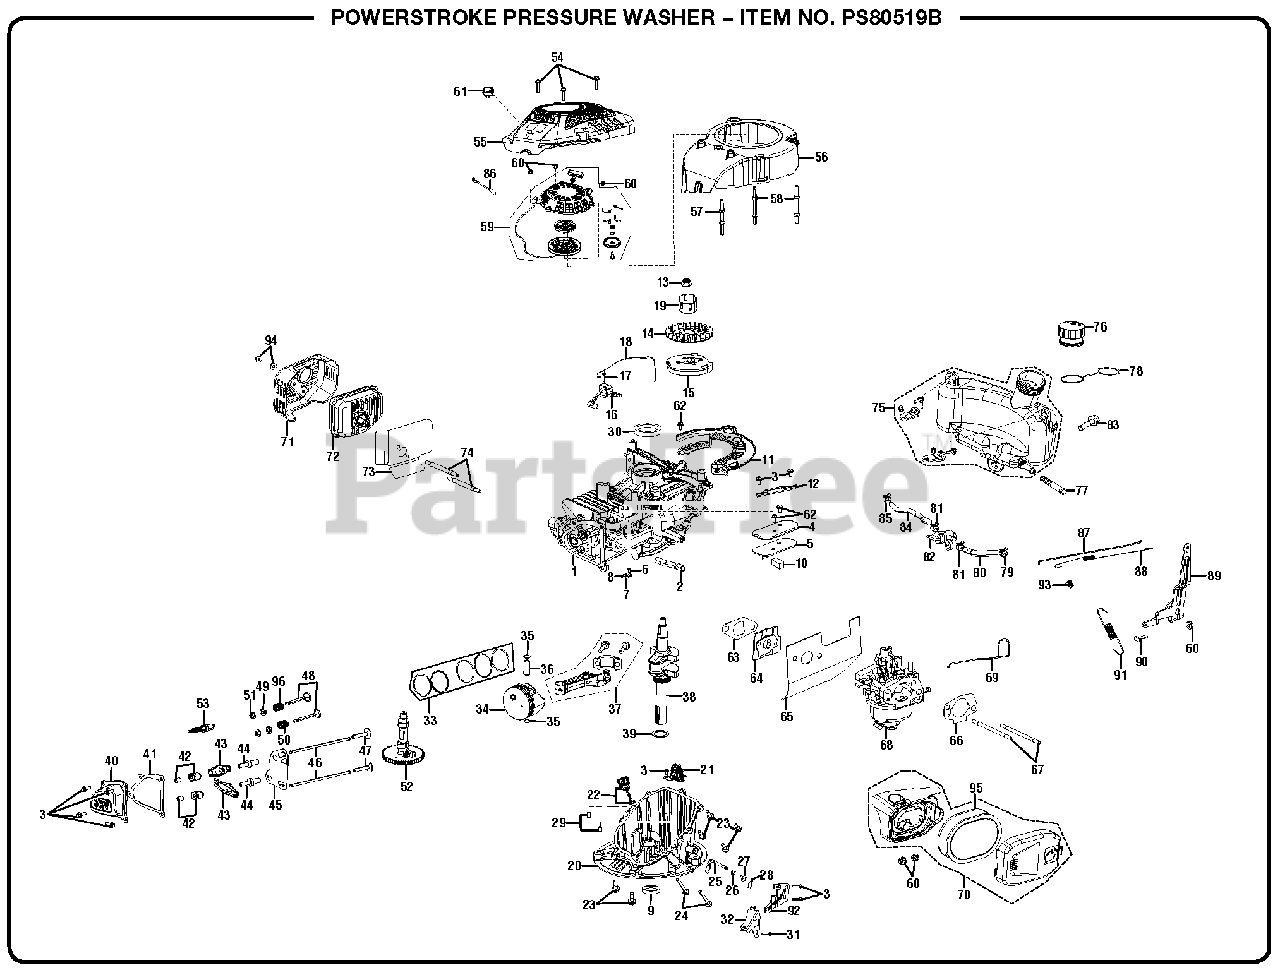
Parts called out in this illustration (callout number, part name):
1	Crankcase Assembly
4	Breathe Groove Cover Plate
5	Breathe Groove Gasket
6	Bolt (Cross-Stitch)
8	Valve Reed Stopping Plate
10	Breathe Groove Strainer
15	Flywheel Subassembly
18	Ignition Coil Wire
20	Crankcase Cover
21	Governor Gear Assembly
22	Dipstick Assembly
35	Piston Pin Clip
38	Crankshaft Assembly
40	Cylinder Head Cover
41	Cylinder Head Cover Gasket
42	Valve Adjusting Nut
44	Valve Adjusting Bolt
49	Valve Spring Seat
52	Camshaft Assembly
59	Recoil Starter Assembly
61	Stop Engine Switch
63	Insulator Plate Gasket
64	Carburetor Insulator Plate
65	Insulator Plate Gasket
66	Carburetor Gasket
68	Carburetor Assembly
71	Muffler Outer Cover
72	Muffler Assembly
73	Exhaust Outlet Gasket
77	Fuel Tank Strainer
78	Fuel Tank Lock Ring
86	Stop Engine Switch Grounding Wire
88	Throttle Valve Returning Spring
89	Governer Support Subassembly
90	Governer Support Bolt
91	Governer Spring
92	Throttle Control Bottom Plate Subassembly
